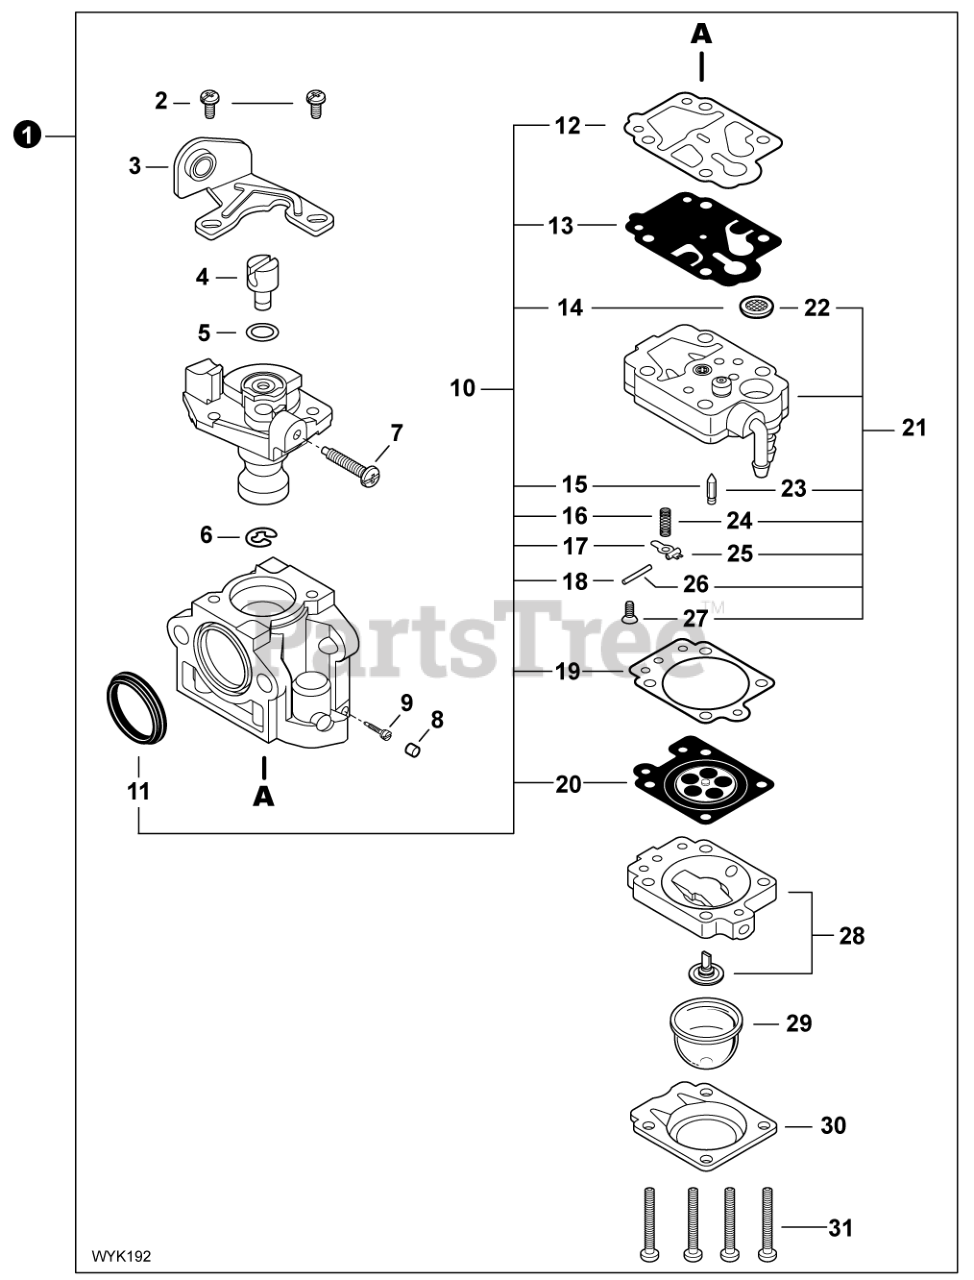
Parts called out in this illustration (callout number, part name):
1	CARBURETOR - WYK-192
3	BRACKET, THROTTLE CABLE
9	NEEDLE, HIGH SPEED
10	REPAIR KIT, CARBURETOR
11	RING, PACKING
12	GASKET, FUEL PUMP
13	DIAPHRAGM, FUEL PUMP
14	SCREEN, FUEL INLET
15	VALVE, INLET NEEDLE
16	SPRING, METERING LEVER
17	LEVER, METERING
18	PIN, METERING LEVER
19	GASKET, METERING DIAPHRAGM
20	DIAPHRAGM, METERING
21	BODY ASSY, PUMP
22	SCREEN, FUEL INLET
23	VALVE, INLET NEEDLE
24	SPRING, METERING LEVER
25	LEVER, METERING
26	PIN, METERING LEVER
27	SCREW
28	BODY ASSY, PURGE
29	BULB, PURGE
30	RETAINER, PURGE BULB
